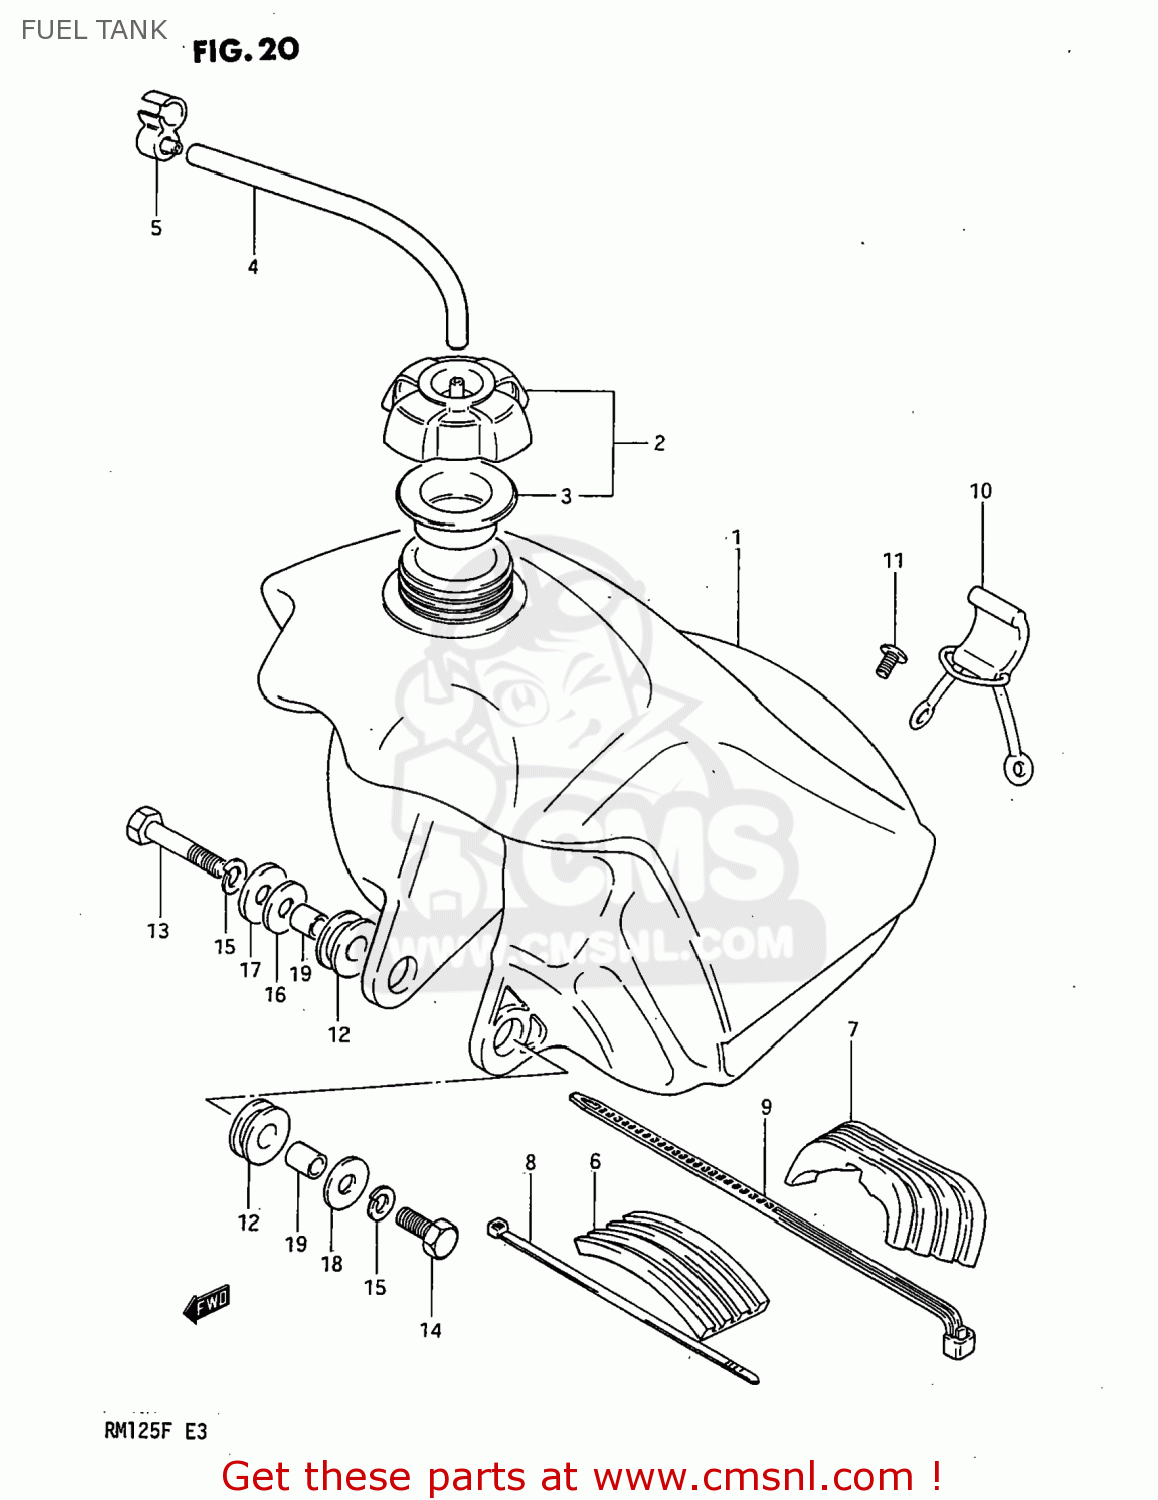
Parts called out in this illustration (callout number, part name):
1	TANK SET,FUEL
2	CAP SET,FUEL TANK
3	GASKET,FUEL TANK CAP (NAS)
4	HOSE
5	CLAMP,BREATHER HOSE
6	CUSHION,FUEL TANK UPR FR
7	CUSHION,FUEL TANK
8	CLAMP
9	CLAMP(L:250)
10	BAND,FUEL TANK RR
11	SCREW (6X15)
12	CUSHION
13	BOLT
14	BOLT (8X30)
15	LOCK WASHER
16	WASHER(8.5X26X1.2)
17	WASHER
18	WASHER
19	SPACER (8.8X12X13.5)
